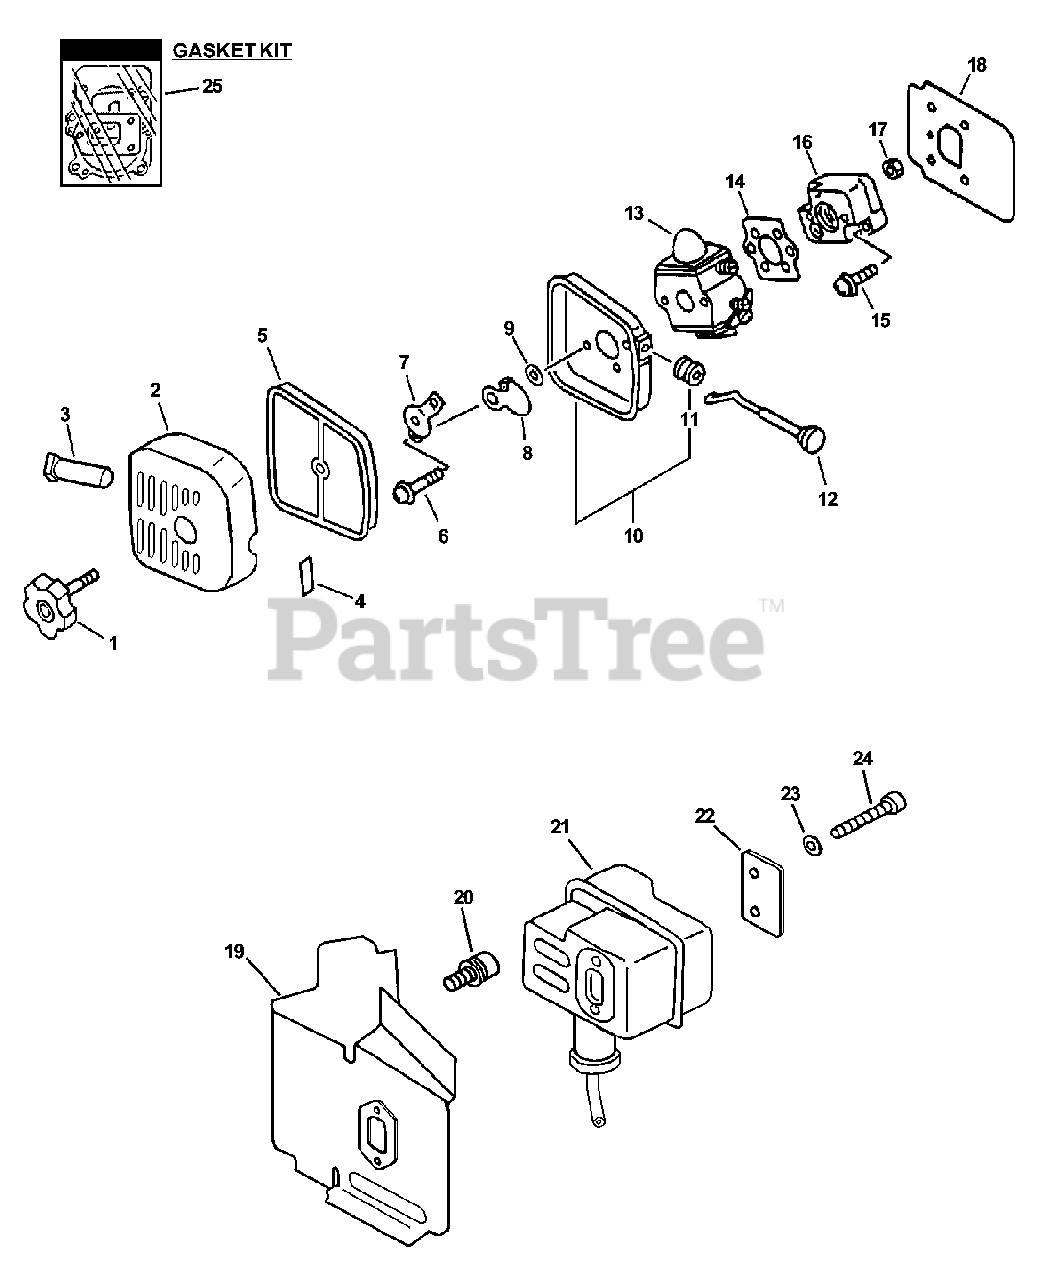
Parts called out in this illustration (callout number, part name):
1	THUMBSCREW
2	COVER, AIR FILTER
4	LABEL - CHOKE
5	FILTER, AIR - HEAVY DUTY
6	SCREW - 5X57
7	PLATE, PREVENT
8	SHUTTER, CHOKE
9	WASHER - 5
10	CASE, AIR FILTER
12	ROD, CHOKE
13	CARBURETOR C1U-K54A
14	GASKET, INTAKE
15	SCREW - 5X20
16	INSULATOR, INTAKE
18	SHIELD, INTAKE
19	SHIELD, EXHAUST
20	SCREW - 4X8
21	MUFFLER
23	WASHER - 5
24	SCREW - 5X70
28	GASKET KIT
